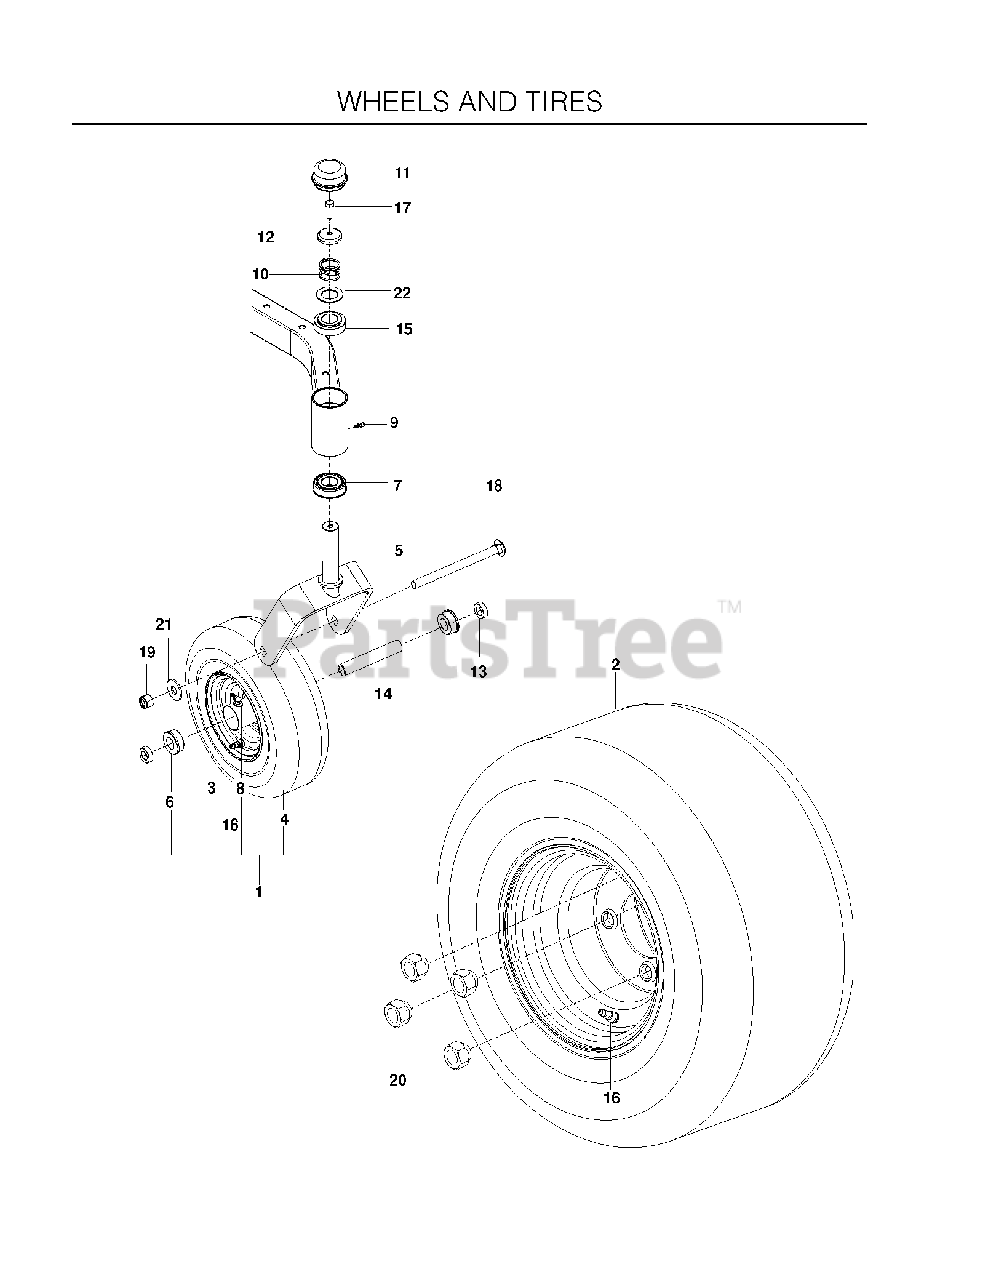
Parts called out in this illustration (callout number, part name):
1	WHEEL ASSY, WIDE, RZ
2	TIRE/WHEEL ASM 18X9.5-8
3	WHEEL 3.0 X 5.0
4	TIRE 11X6-5, 4 PLY
5	CASTER DK BLUE
6	BUSHING, WHEEL, 3/4"
7	BEARING FLANGED
8	ZERK
9	ZERK, 3/16, DRIVE IN
10	SPRING, CASTER
11	GREASE CAP
12	CASTER.PLUG
13	SPACER, 5/16"
15	BUSHING, CASTER
16	VALVE STEM TR-412
17	5/16-18X1 HHB G5W/NY
18	RHSNB 1/2-13 X 6.50 GR2 ZD
19	NUT 1/2-13 HEX CNTRLK GR 5 ZD
20	LUG NUT 1/2F
21	WASH USS FLAT 1/2
22	WASHER, 1.025 ID X 1.64
